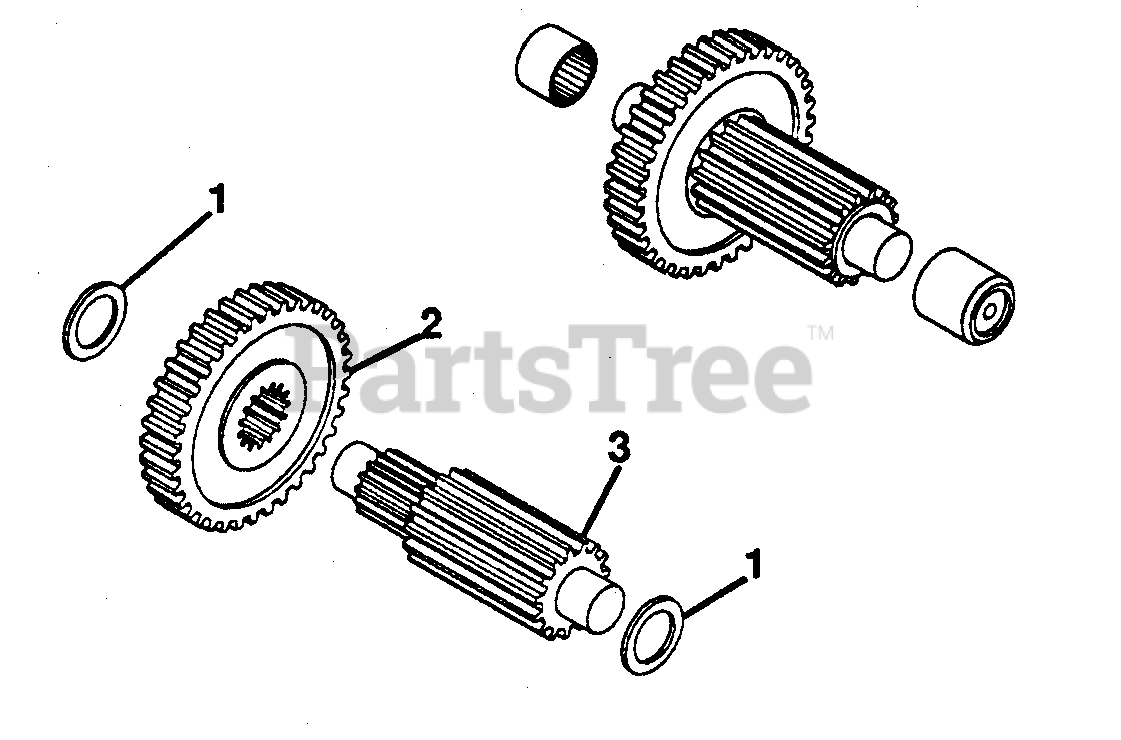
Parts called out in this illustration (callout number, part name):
1	Race, Brg Thrust 1.002 x 1.552 x .03
2	Gear, 8 DP 30 Teeth x .750
3	Pinion, Final Drive
